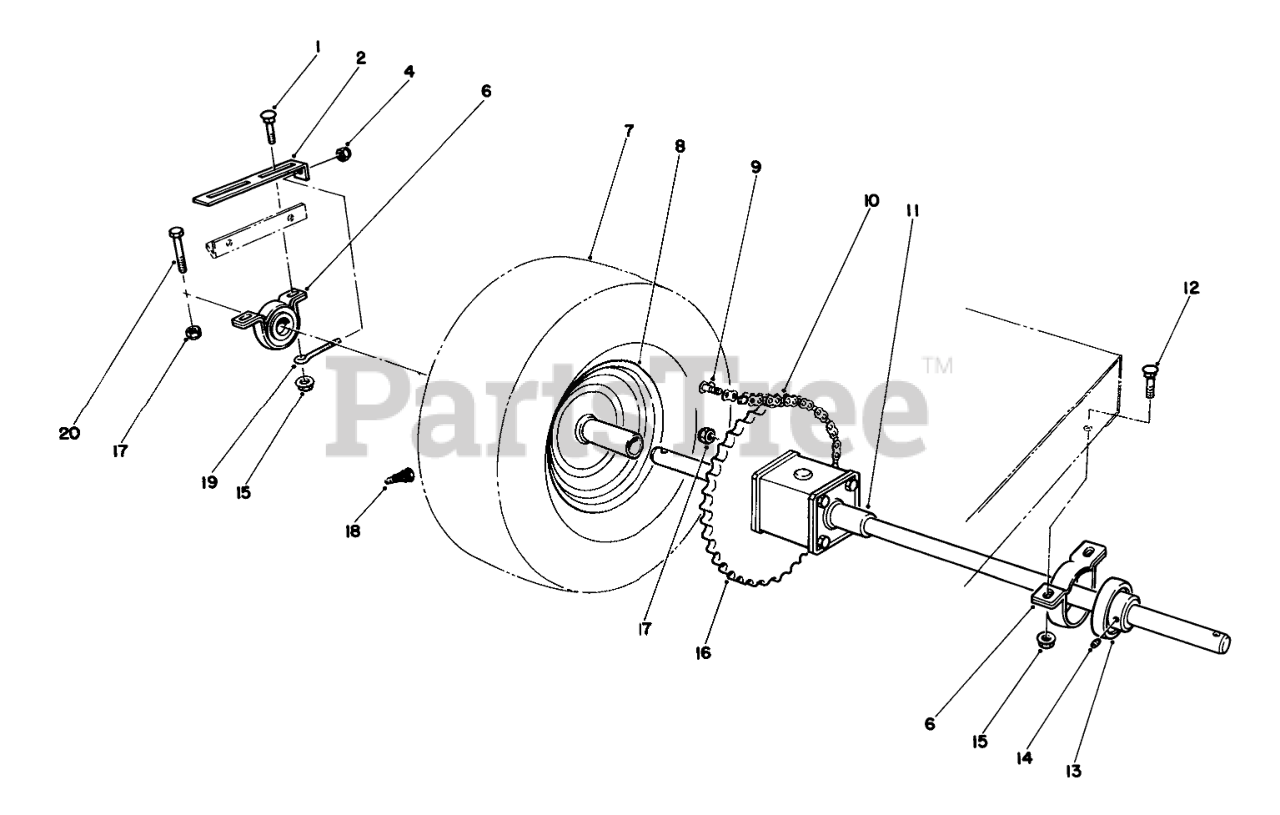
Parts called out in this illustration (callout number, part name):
1	BOLT-CARR
2	PLATE-ADJUSTING
4	NUT-LOCK, NI
6	RTNR-PILLOW BLK
7	TIRE,PNEU.13X5.00X6
8	WHEEL-REAR
9	LINK-CHAIN
10	Chain (Incl. Ref. #9)
11	Differential
12	Bolt-Carriage
13	Bearing (Incl. Ref. #14)
14	SCREW-HSH
15	NUT-HF
16	45 T SPROCKET
17	NUT-LOCK, NI
18	STEM-VALVE
19	SCREW-ADJUSTING
20	Bolt
